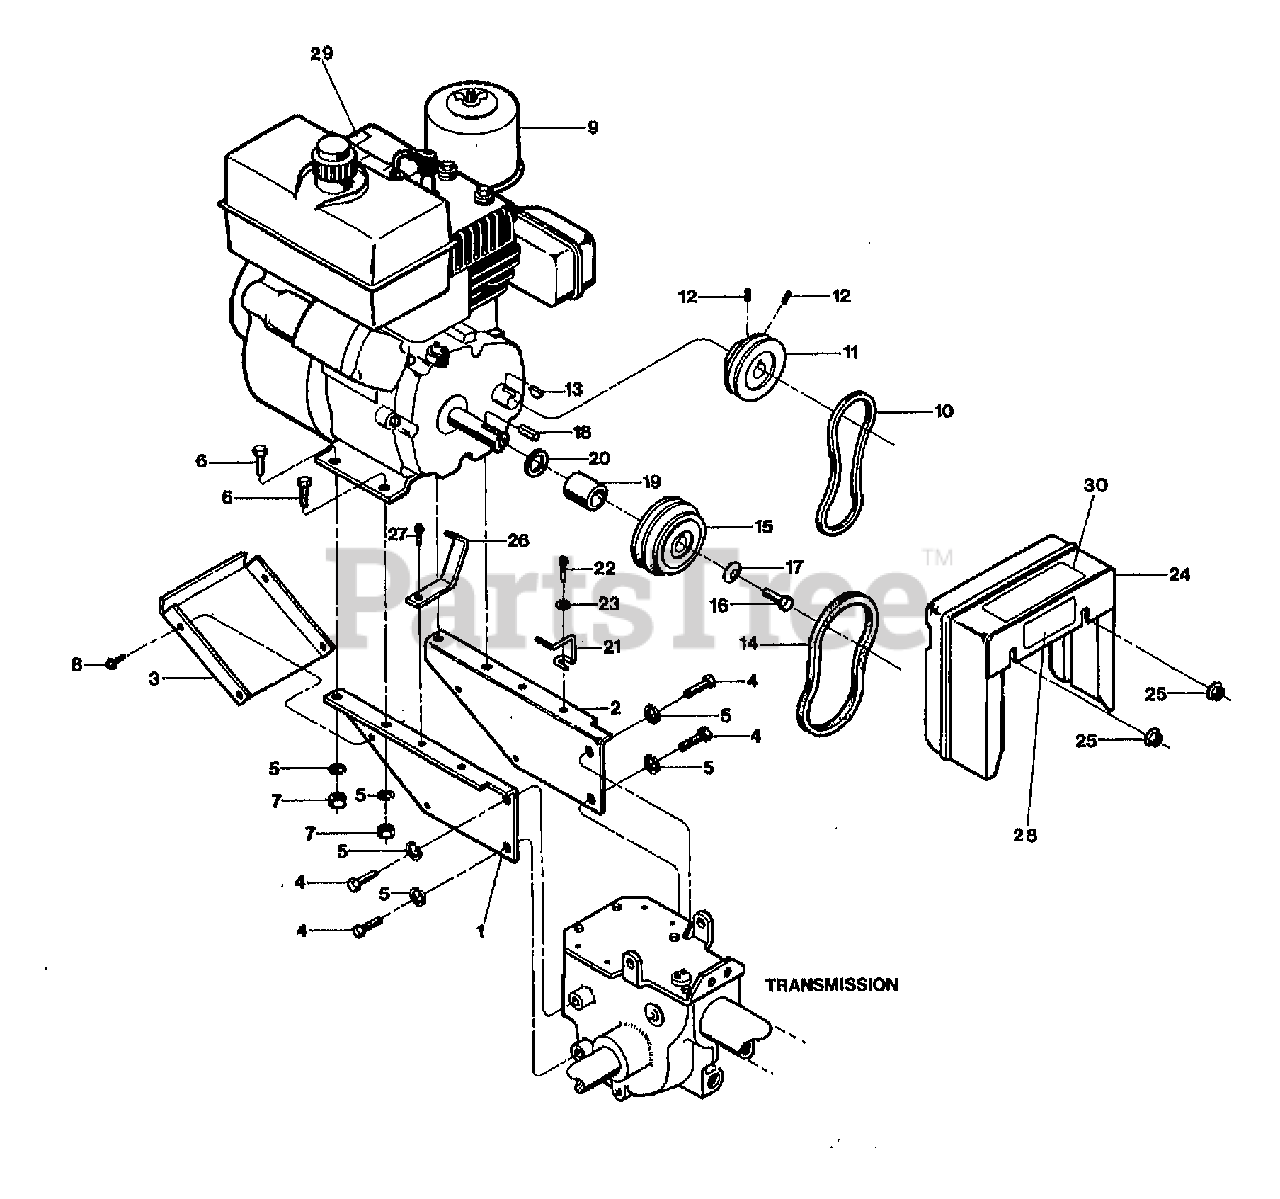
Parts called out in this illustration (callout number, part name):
1	BRKT-ENG LT P4
2	BRKT-ENG RT PNT
3	PAN-ENG BRKT PNT
4	SCR-HFLK 5/16-18X.75 ZP
5	WASHER-LK .312 ZP
6	SCR-HHC 5/16-18X.75 GR 5 ZP
7	NUT-HEX 5/16-18 ZP
8	SCR-HH SEMS 10-32 X .5 ZP (W/PERMANET WASHER)
9	ENGINE, TECUMSEH, 6HP RECOIL START,
10	BELT-V REV DR ECONO (SEE V-BELT BELOW)
11	PULLEY-REV MACH
12	SCR-SS 1/4-20 X .25 (SECURES REVERSE ENGINE PULLEY)
13	KEY-WOODRUFF #5
14	BELT-V GROOVE FWD SMFRAME (SEE V-BELT BELOW)
15	PULLEY-ENGINE MACH
16	SCR-HH 3/8-24X1.0 G5 ZP (SECURES FORWARD ENGINE PULLEY)
17	WASHER-.994X.413X.145
18	KEY-.188 SQX1.0
19	SPACER-.937X.755X.938
20	SHIM-1.0X.7656X.031
21	GUIDE-BELT FWD
22	SCR-HWH 1/4-20 X .75 STH
23	WASHER-FLAT 1/4 SAE
24	COVER-W/DECALS-ECONO OPC (INCL. 28 & 30)
25	NUT-HFLK 5/16-18 ZP (WHIZ-STYLE)
26	GUIDE-BELT REV PNT
27	SCR-HWH 1/4-20 X .5 STH
28	DECAL-BELT CHG ECONO OPC
29	DECAL-STARTING STABIL
30	DECAL-BELT COVER OPC
